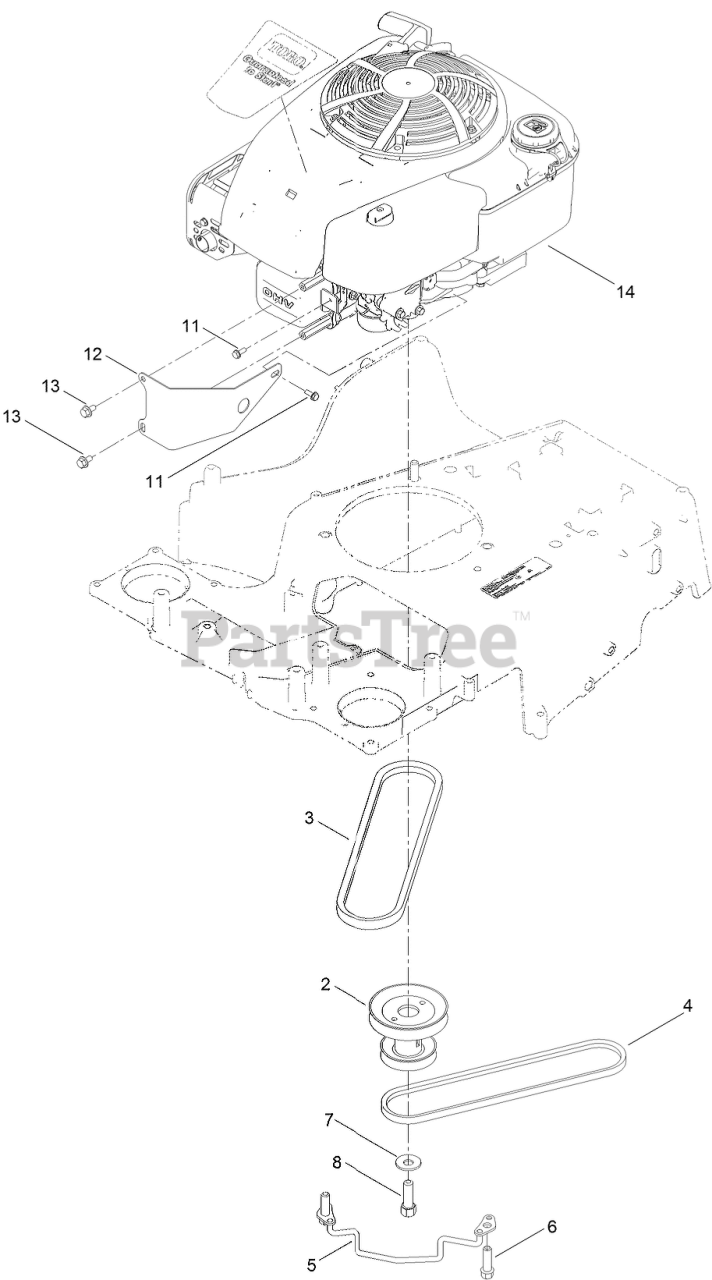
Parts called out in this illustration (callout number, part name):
2	PULLEY-ENGINE
3	V-BELT
4	V-BELT, TRACTION
5	GUIDE-BELT
6	SCREW-TAPTITE
7	WASHER-BELLEVILLE
8	SCREW-HH
11	SCREW-TAPTITE
12	GUARD-ENGINE
13	SCREW-HHF
